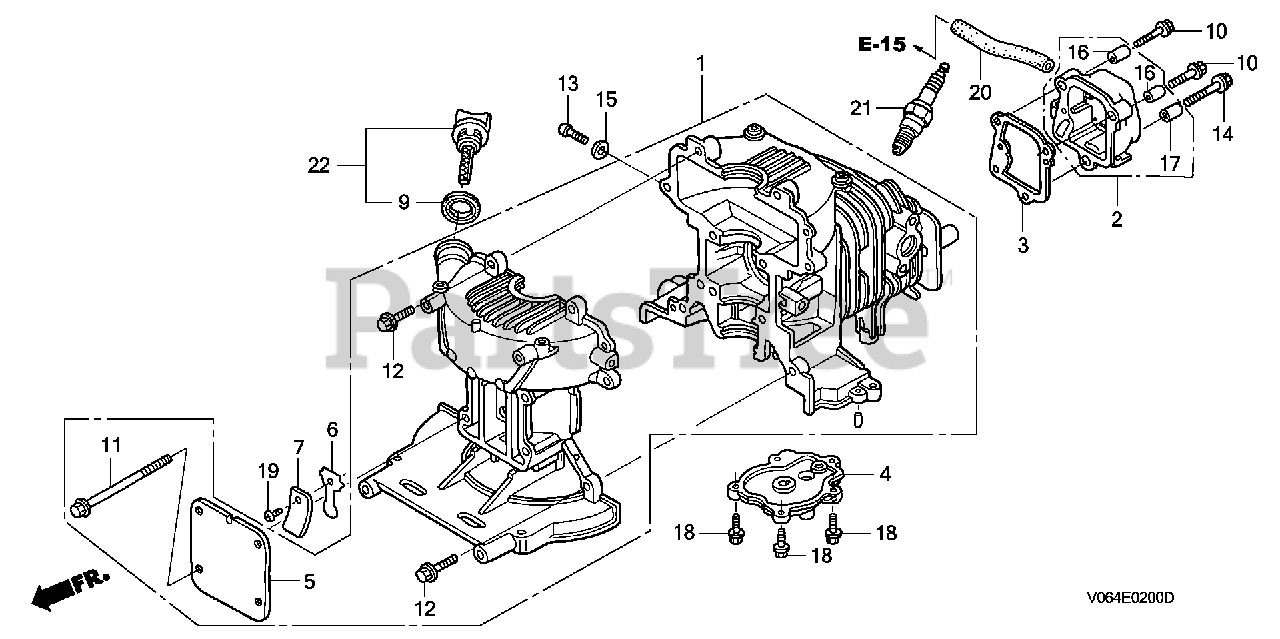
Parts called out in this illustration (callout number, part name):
1	CRANKCASE SET
2	COVER, HEAD
3	GASKET, HEAD COVER
4	COVER, CAMSHAFT
5	COVER, OIL OUTLET VALVE
6	VALVE, OIL OUTLET
7	PLATE, STOPPER
9	GASKET, OIL FILLER CAP
10	BOLT, FLANGE (5X22)
11	BOLT, FLANGE (5X55)
12	BOLT, FLANGE (5X18)
13	SCREW, PAN (6X8)
14	BOLT, FLANGE (5X14)
15	WASHER, SEALING (6.5MM)
16	COLLAR, HEAD COVER
17	COLLAR A, HEAD COVER
18	BOLT-WASHER (4X16)
19	SCREW, PAN (3X5)
20	BULK HOSE, VACUUM (7X3000) (7X68)
21	SPARK PLUG (CR5HSB)
22	CAP ASSY., OIL FILLER
